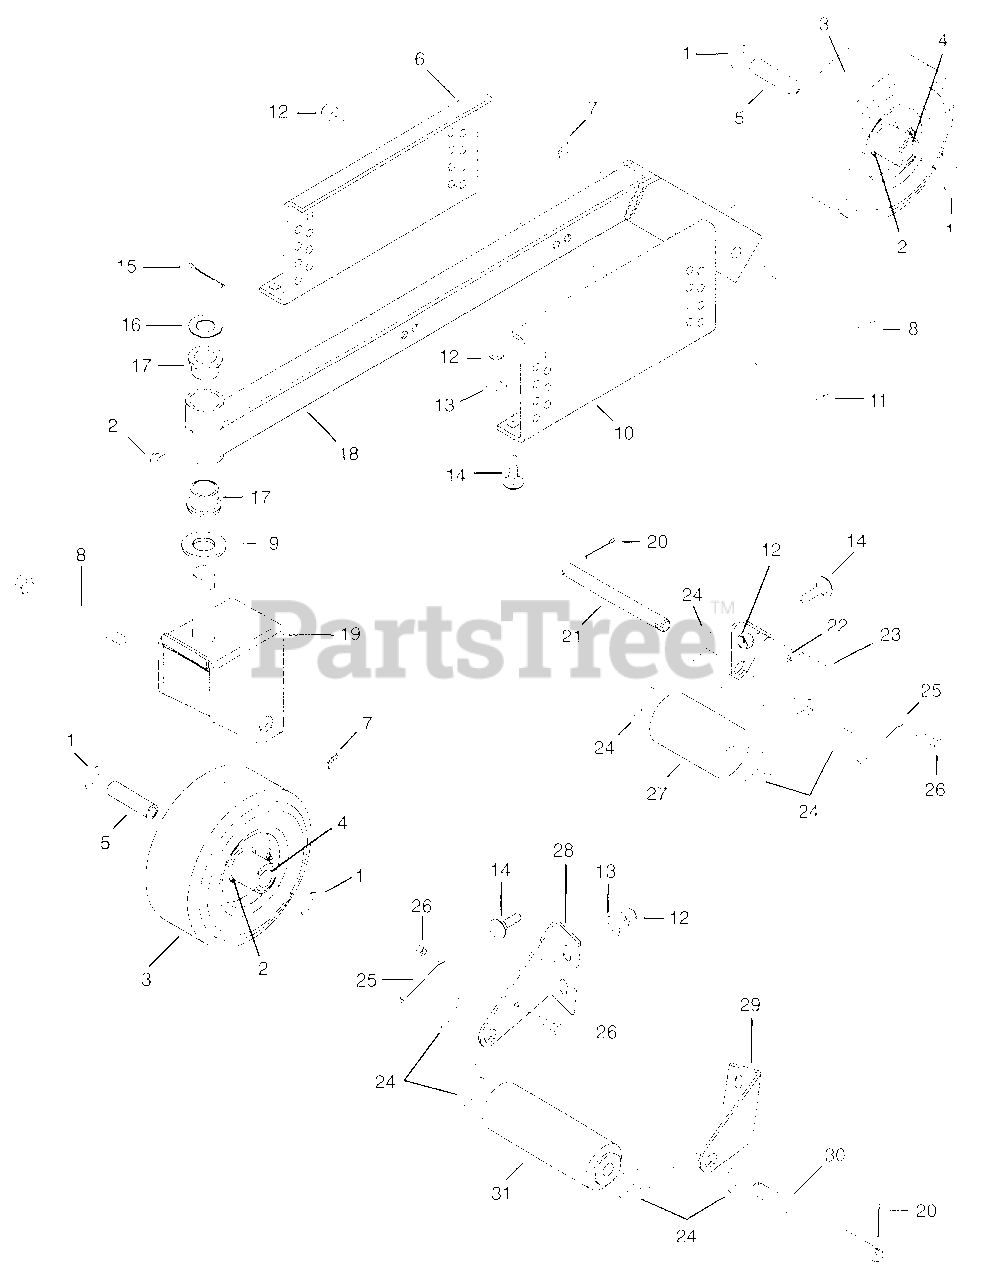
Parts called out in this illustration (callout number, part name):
1	Washer - Flat - Steel .531 x 1.250 x .100
2	Fitting - Lube .25-28 x .256
3	Wheel 9 x 3.50
4	Bearing-Ball .752 x 1.50 x .50
5	Spacer .532 x .748 x 3.34
6	Hanger-Left Hand
7	Nut-Locking-Nylon .50-13 Grade 5
8	Bolt-Hex .50-13 x 5.00
9	Washer-Flat-Steel 1.007 x 1.542 x .062
10	Hanger-Right Hand
11	Bolt-Hex .38-16 x 2.50 Grade 5
12	Nut-Locking-Nylon .375-16 Grade 2
13	Washer-Flat-Steel .406 x .812 x .065
14	Bolt-Round Head Square Neck .38-16 x 1.0
15	Pin-Cotter .188 x 1.625
16	Washer-Hardened-Thrust 1.00 x 1.55 x .030
17	Bushing-Flange 1.020 x 1.385 x .75 x 1.75
18	Weldment-Caster Wheel Support
19	Weldment-Caster Fork
20	Pin-Cotter .25 x 1.00
21	Rod
22	Nut-Hex .250-20 Grade 2
23	Bracket-Roller
24	Washer-Flat-Steel .656 x 1.312 x .095
25	Pin-Cotter .250 x 2.00
26	Bolt-Hex .25-20 x .75 Grade 5
27	Roller-Gage
28	Bracket-Roller Right Hand
29	Bracket-Roller Left Hand
30	Shaft-Center Roller
31	Roller-Gage
